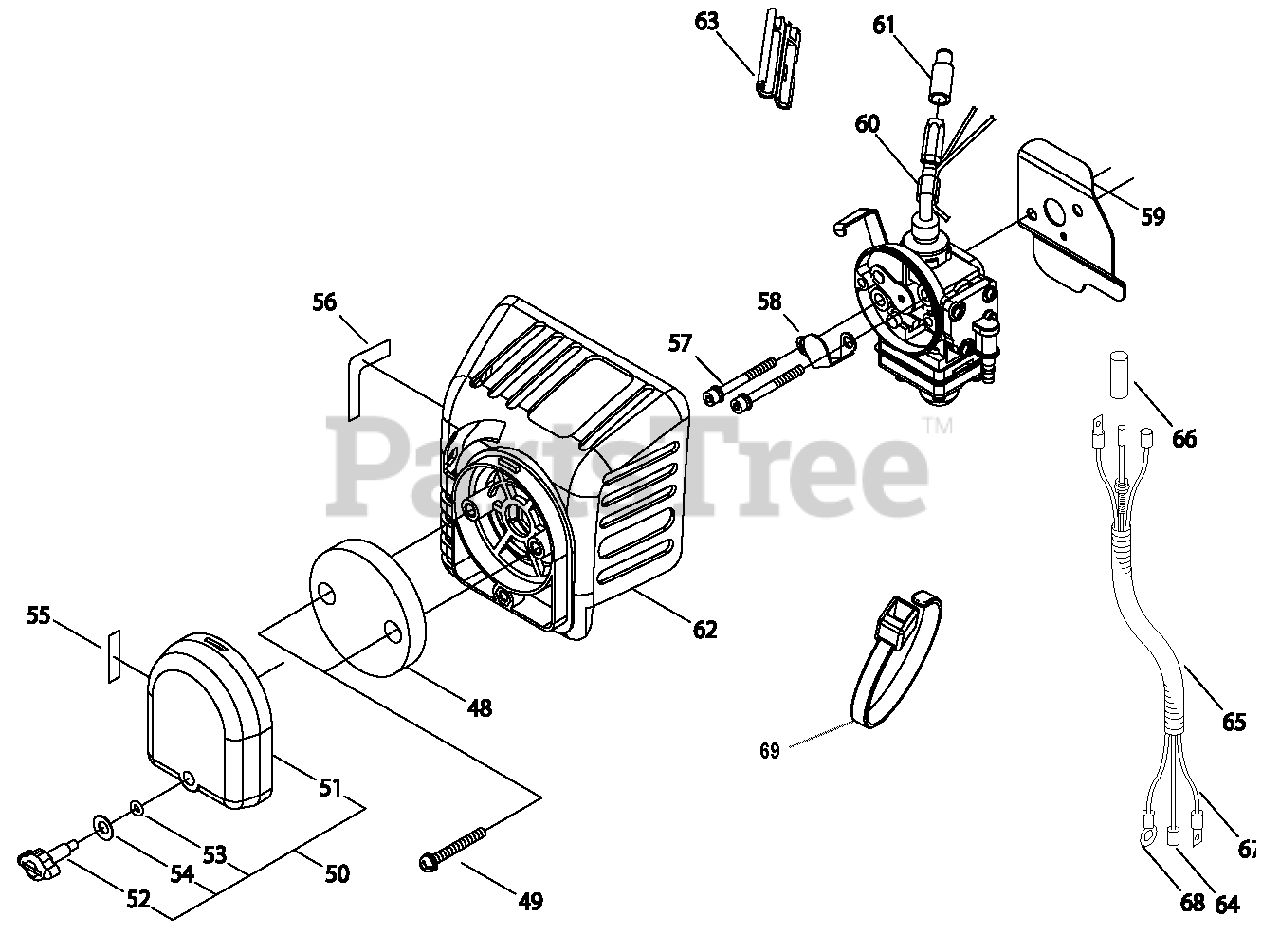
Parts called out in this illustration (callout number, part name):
48	FILTER, AIR
49	SCREW - 4X25
50	COVER KIT - AIR FILTER
51	COVER, AIR FILTER
52	THUMBSCREW
53	O-RING
54	WASHER - CONICAL
55	LABEL - CHOKE
56	LABEL - CARBURETOR
57	SCREW
58	PLATE
59	GASKET, INTAKE
60	TUBE
61	CAP, CABLE
62	CASE, AIR FILTER
63	CONNECTOR TUBE
64	CONNECTOR, CABLE
65	TUBE
66	SLEEVE
67	WIRE
68	WIRE
69	TIE, CABLE
